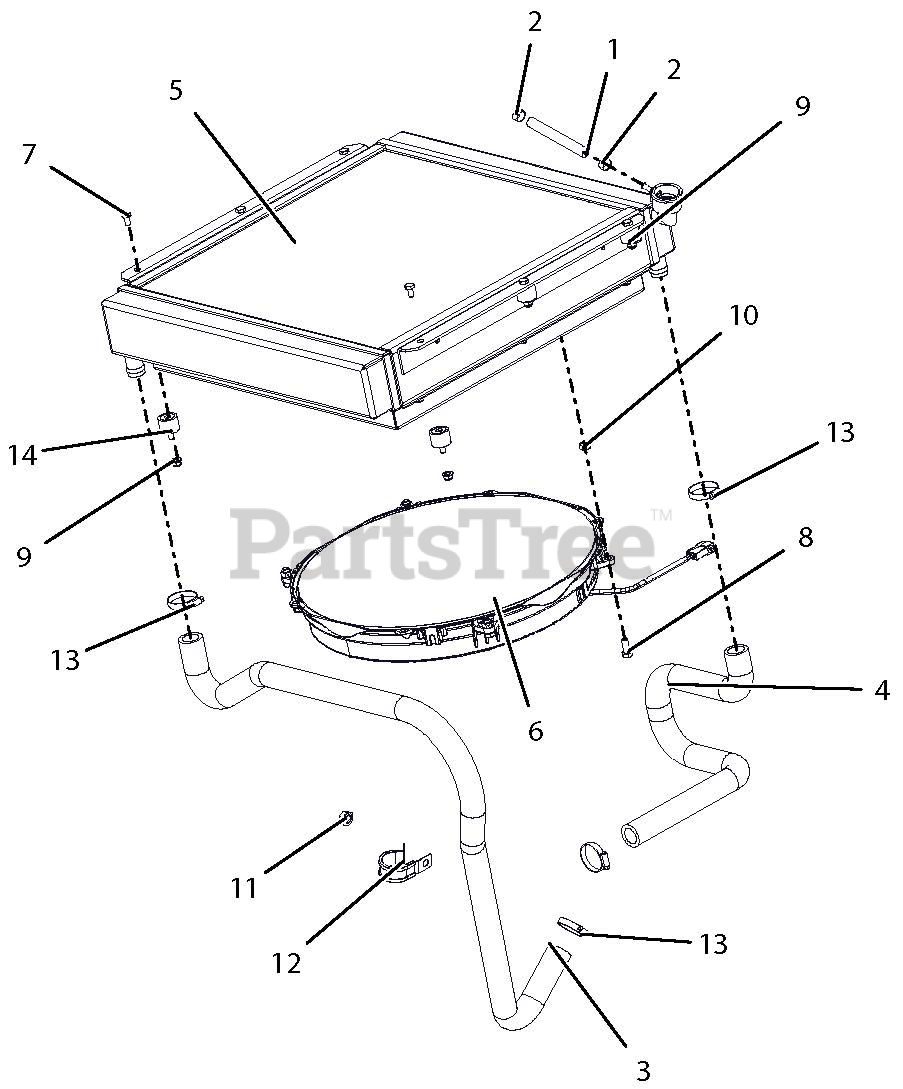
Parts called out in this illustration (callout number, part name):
1	.25 LOW-PERM GAS HOSE 38.00" LG - RADIATOR OVERFLOW TO TANK
2	CLAMP, FUEL LINE
3	HOSE, FORMED RADIATOR OUTLET
4	HOSE, FORMED RADIATOR INLET
5	RADIATOR, DIESEL PT-400
6	FAN, COOLING 16"
7	BLT-HEX .25-20X.50 GR5 YWZC EP80
8	BLT-HEX .31-18X.75 GR5 YWZC
9	NUT-LK-NYL-FLG .25-20 YWZC
10	NUT-LK-CTR .31-18 YWZC
11	@NUT-SPNLK-FLG .375-16 YWZC
12	CLAMP, CUSHIONED STEEL, 1.25
13	CLAMP, HOSE 1.50 X .81 X 1.42
14	ISOLATOR, RUBBER RADIATOR
